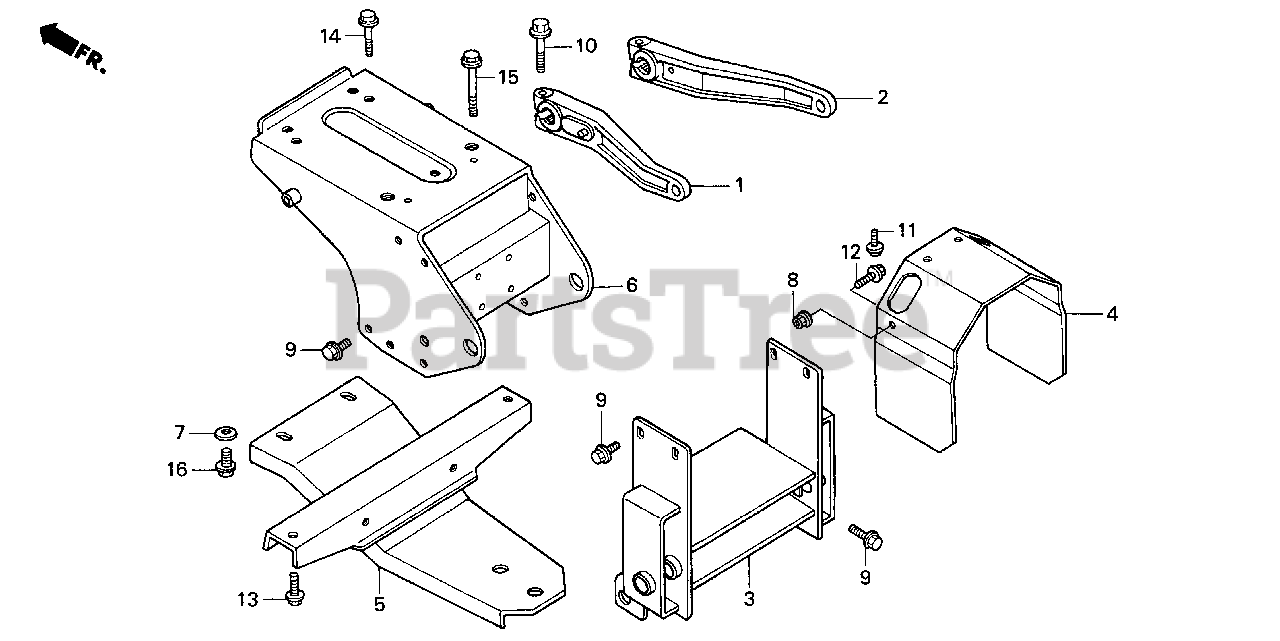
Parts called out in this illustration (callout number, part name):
4	SHIELD, RR. P.T.O. MASTER
5	PLATE, DRAWING
6	PLATE, HYDRAULIC CYLINDER MOUNTING
7	WASHER, PLAIN (12MM)
8	NUT, FLANGE (10MM)
9	BOLT, FLANGE (10X25)
11	BOLT, FLANGE (8X14)
12	BOLT, FLANGE (10X20)
13	BOLT, FLANGE (10X22)
14	BOLT, FLANGE (10X50)
15	BOLT, FLANGE (10X70)
16	BOLT, FLANGE (12X30)
